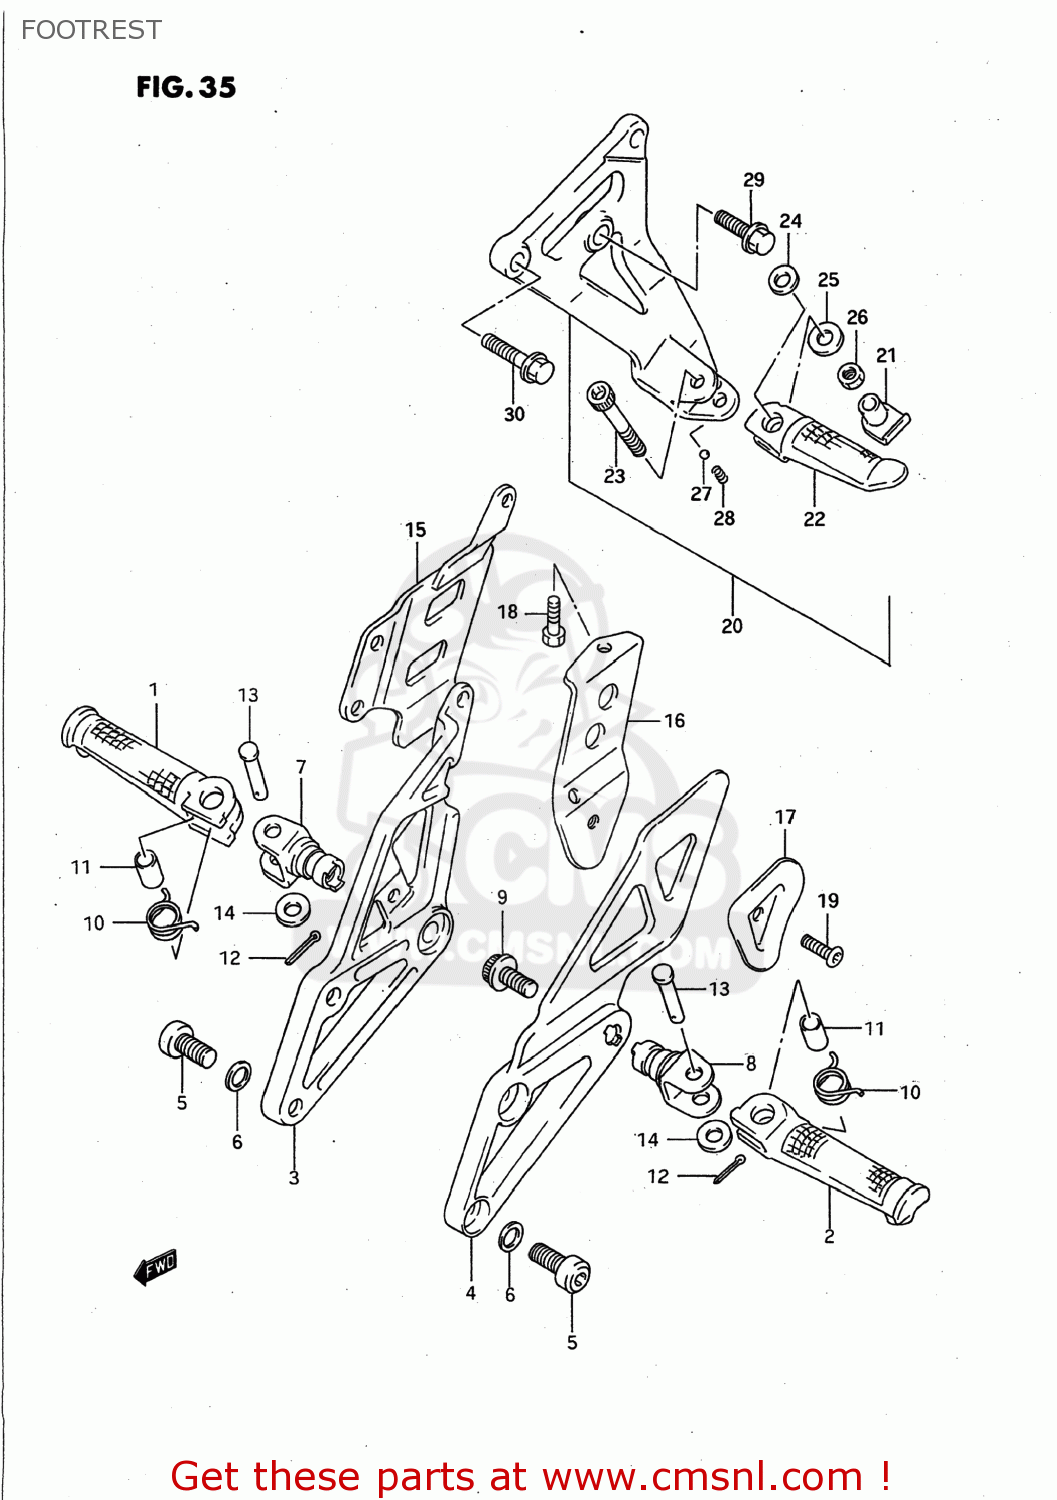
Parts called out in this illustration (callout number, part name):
1	BAR,FOOTREST,R
2	BAR,FOOTREST,L
3	BAR,FRONT FOOTREST
4	BRACKET,FRONT FOOTREST
5	BOLT
6	WASHER
7	HOLDER,FOOTREST,RIGHT
8	HOLDER,FOOTREST,L
9	BOLT(10X24)
10	SPRING
11	SPACER(8.1X12X22)
12	PIN 20X15
13	PIN
14	WASHER(8.5X18X1)
15	GUARD,FRONT FOOTREST,RIGHT
16	REINFORCEMENT,FOOTREST,L
17	PLATE,REINFORCEMENT,L
18	BOLT
19	SCREW(6X12)
20	FOOTREST ASSEMBLY,PILLION
21	BOSS,PILLION FOOTREST,R
22	BAR,PILLION FOOTREST R
23	BOLT
24	WASHER(8.5X18X1)
25	WASHER
26	NUT
27	BALL
28	SPRING
29	BOLT
30	BOLT
